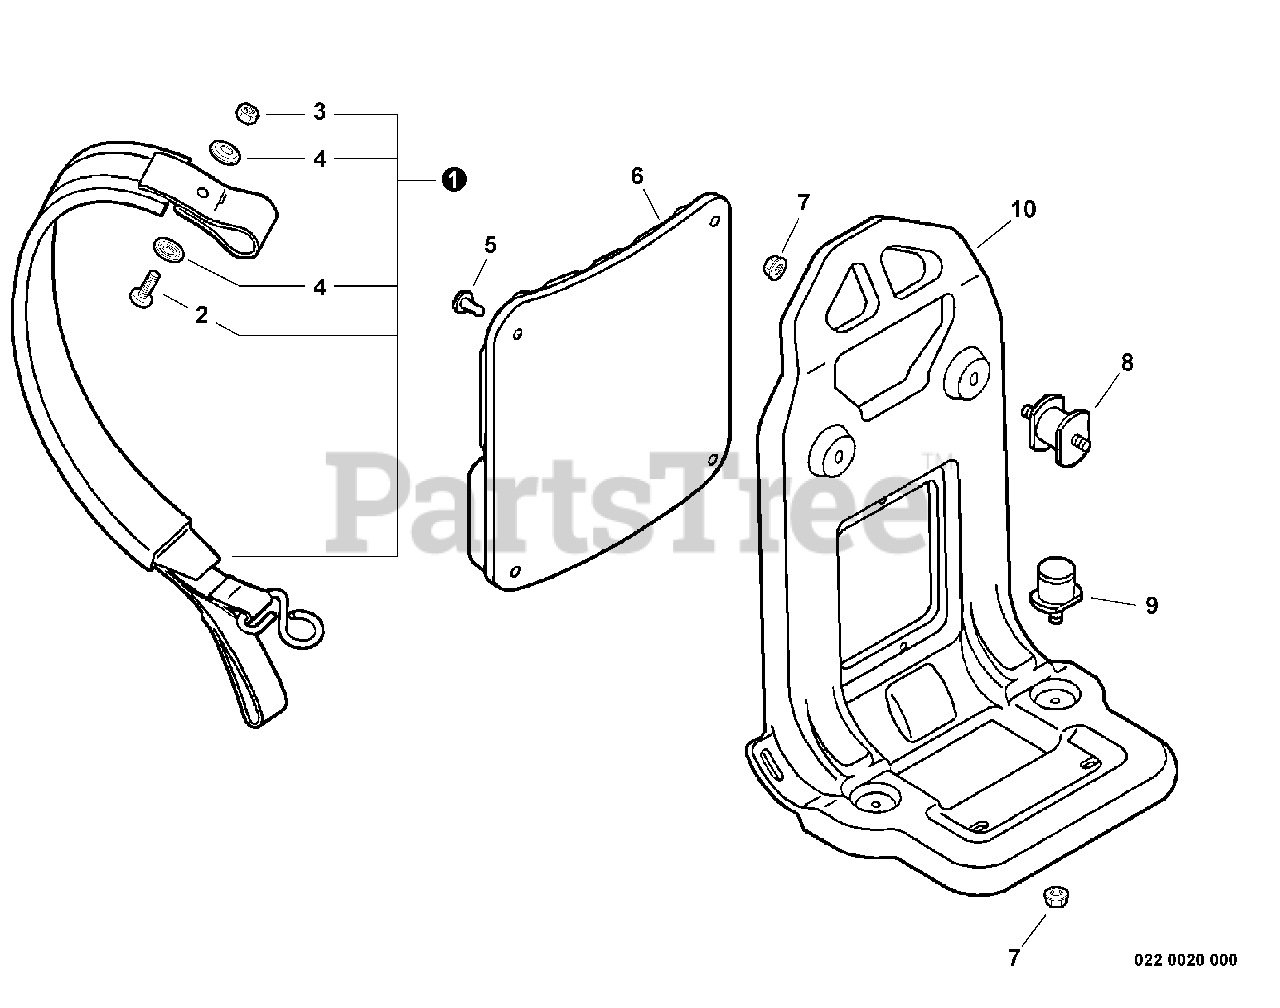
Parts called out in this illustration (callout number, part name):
1	HARNESS ASSY
2	SCREW 5×16
3	NUT, LOCK M5
4	WASHER 5.2×22×2.0
6	CUSHION, BACKPACK
8	CUSHION 6
9	CUSHION 6
10	FRAME, BACKPACK
